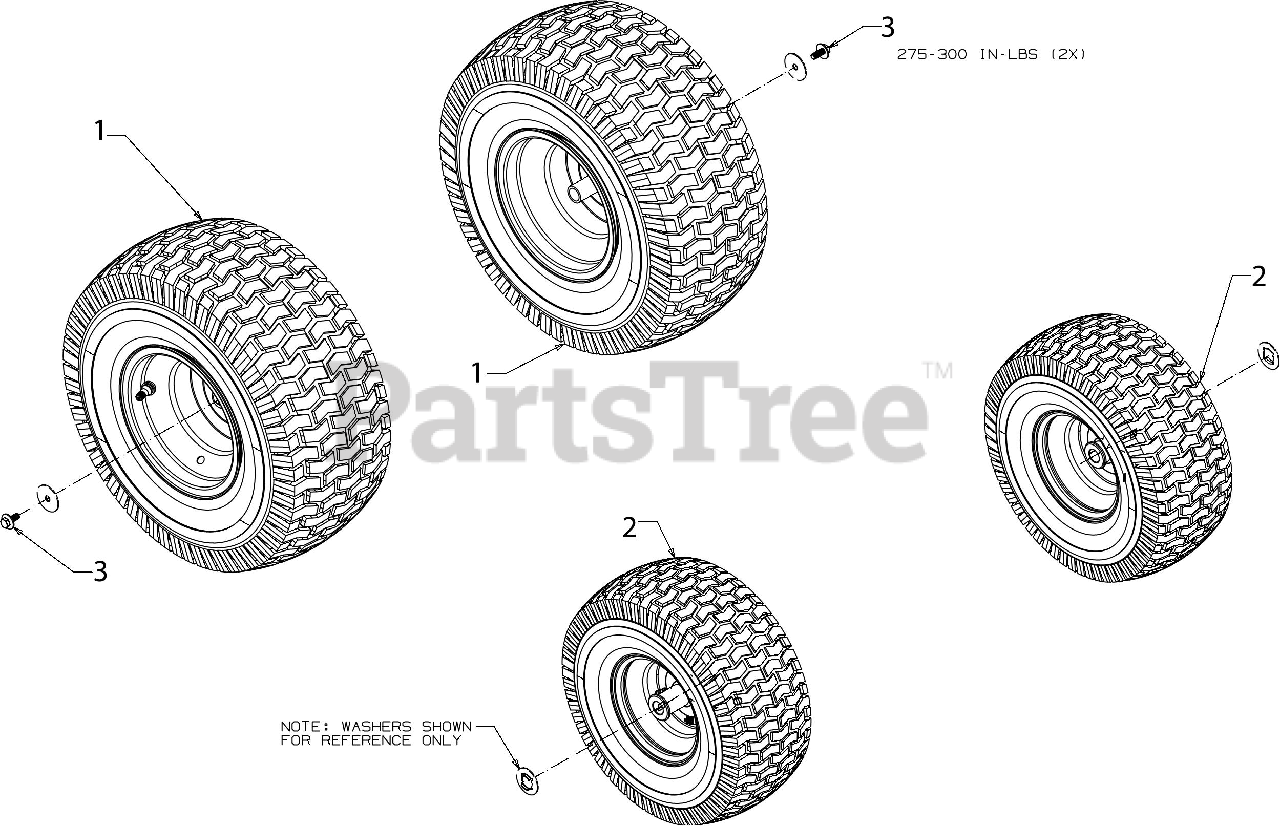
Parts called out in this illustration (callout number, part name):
1	WHEEL ASSEMBLY (20 x 8 x 8)
2	WHEEL ASSEMBLY (15X6X6)
3	SCREW 5/16-24 x .85 GR5
